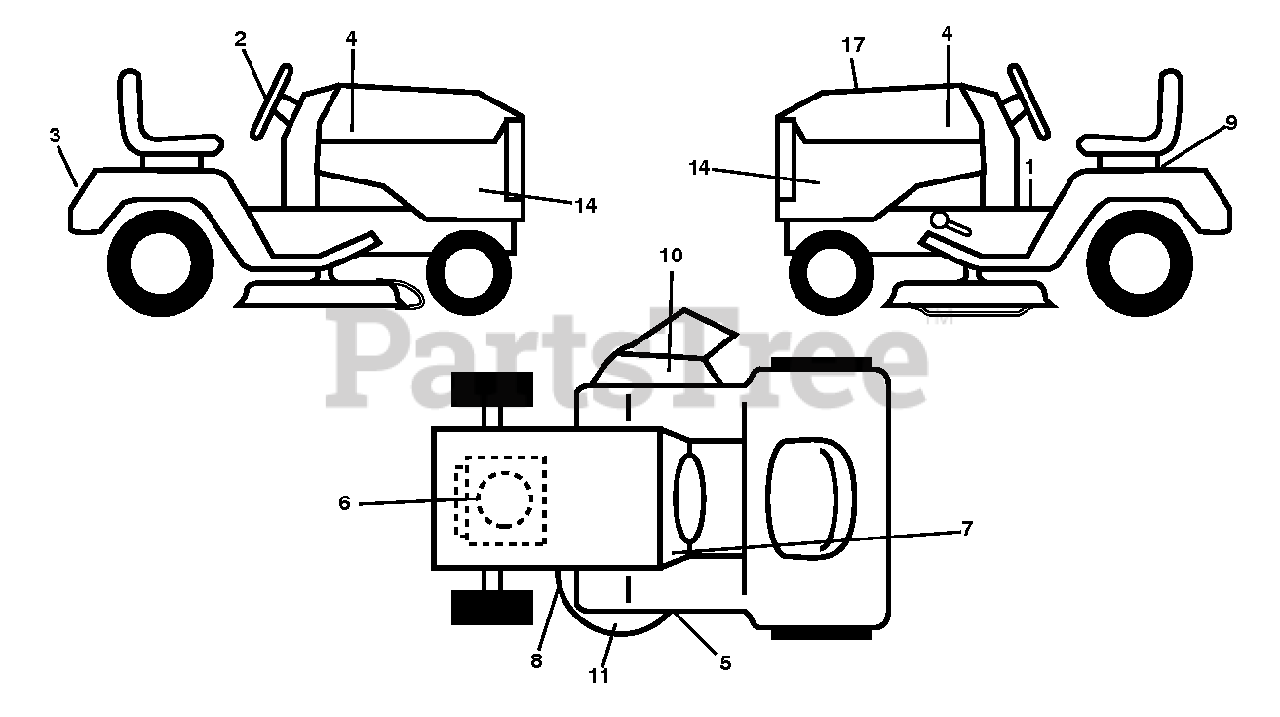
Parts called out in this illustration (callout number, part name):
1	DECAL.FENDER.WARNING.ENGLISH
2	DECAL.STRWHL.BLK.2014.PPRO
3	DECAL.REARFNDR.POULAN PRO.2015
4	DECAL.POULAN PRO.2015
5	DECAL.MOWER.CAUTION.TENSION.AR
6	Decal, Engine BS INTK 24HP 382016
7	DECAL.DASH.SNOWFLAKE.BLACK.SM
8	DECAL.MOWER.SCH.48/54.PREM
9	DECAL BTRY SYMBOLS
10	DECAL, DECK DEFLECTOR, WARNING
11	DECAL.PPRO.10YRDECKWAR.POP
14	DECAL.SDPNL.PB24VA54.BLK.PPRO
17	DECAL.RPL.BSM44.TLW.54.GENTR
